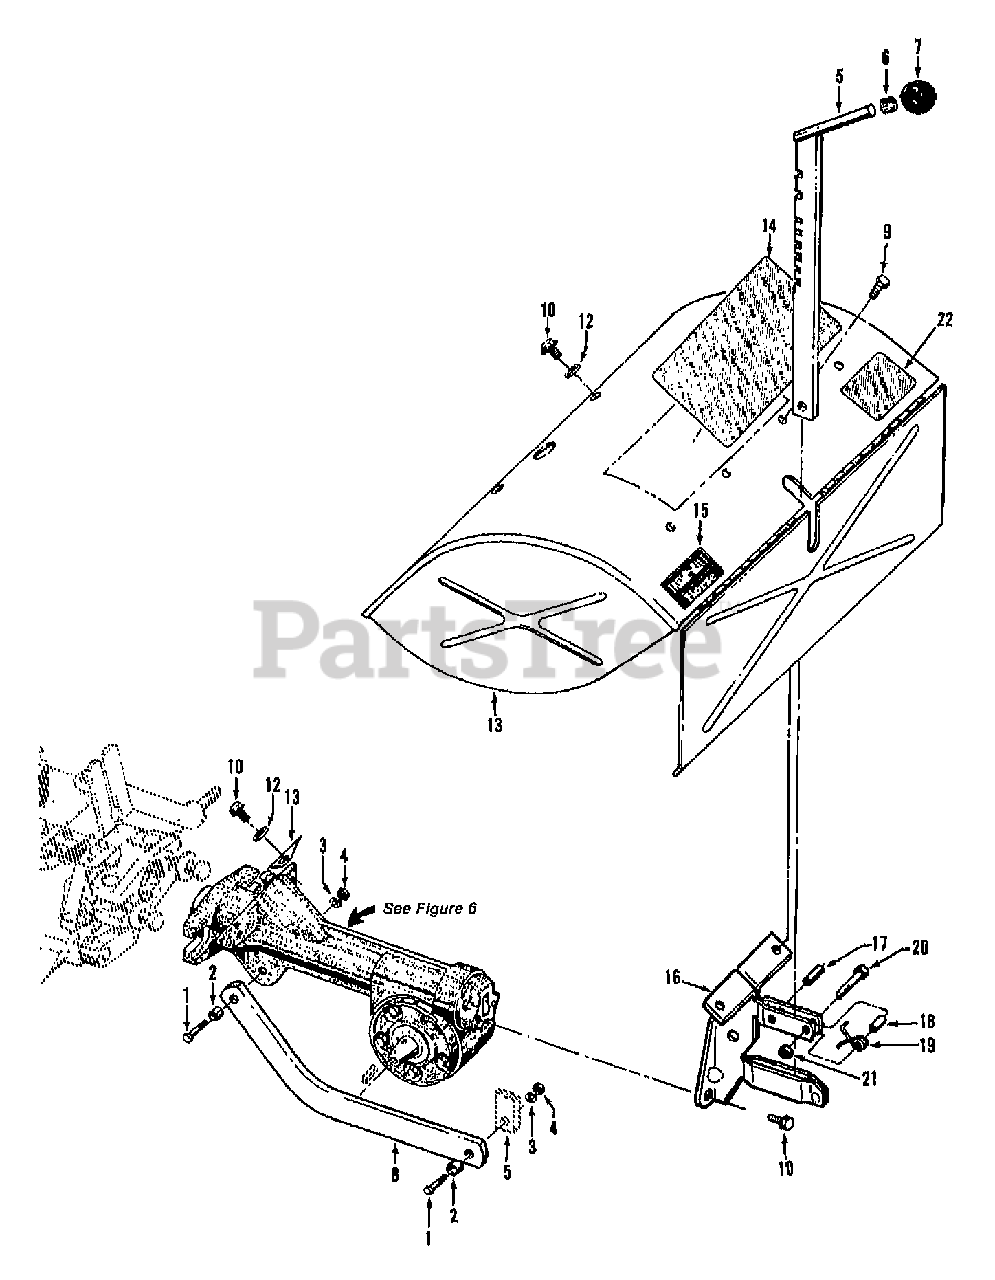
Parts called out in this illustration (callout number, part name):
1	SCR-HH 3/8-16X1.25
2	BUSHING-.5X.375X.3
3	WASHER-LK .375 @ DEPL
4	NUT-HEX 3/8-16 ZP
5	DEPTH REGULATOR W/KNOB #9119 (#7) & #9120 ( #6)
6	RING-TOLERANCE .5325 ID
7	KNOB-CONTROL
8	BAR-DRAG RED
9	SCR-HWH 1/4-20 X .5 STH
10	SCR-HFLK 5/16-18X.75 ZP
12	WASHER-#1.125X.344 ZP
13	HOOD W/DECALS OPC SERVICE (#'s 14, 15 & 22)
14	DECAL-HOOD INST OPC
15	DECAL-HORSE LOGO OPC
16	BRKT W/ROLL PIN (9308)
17	PIN-ROLL .25 X 1
18	SPACER-.250X.343X.375
19	SPRING-TORSION
20	SCR-HH 1/4-20X1.0
21	NUT-LK 1/4-20
22	DECAL-TINE WARN SM FRAME
